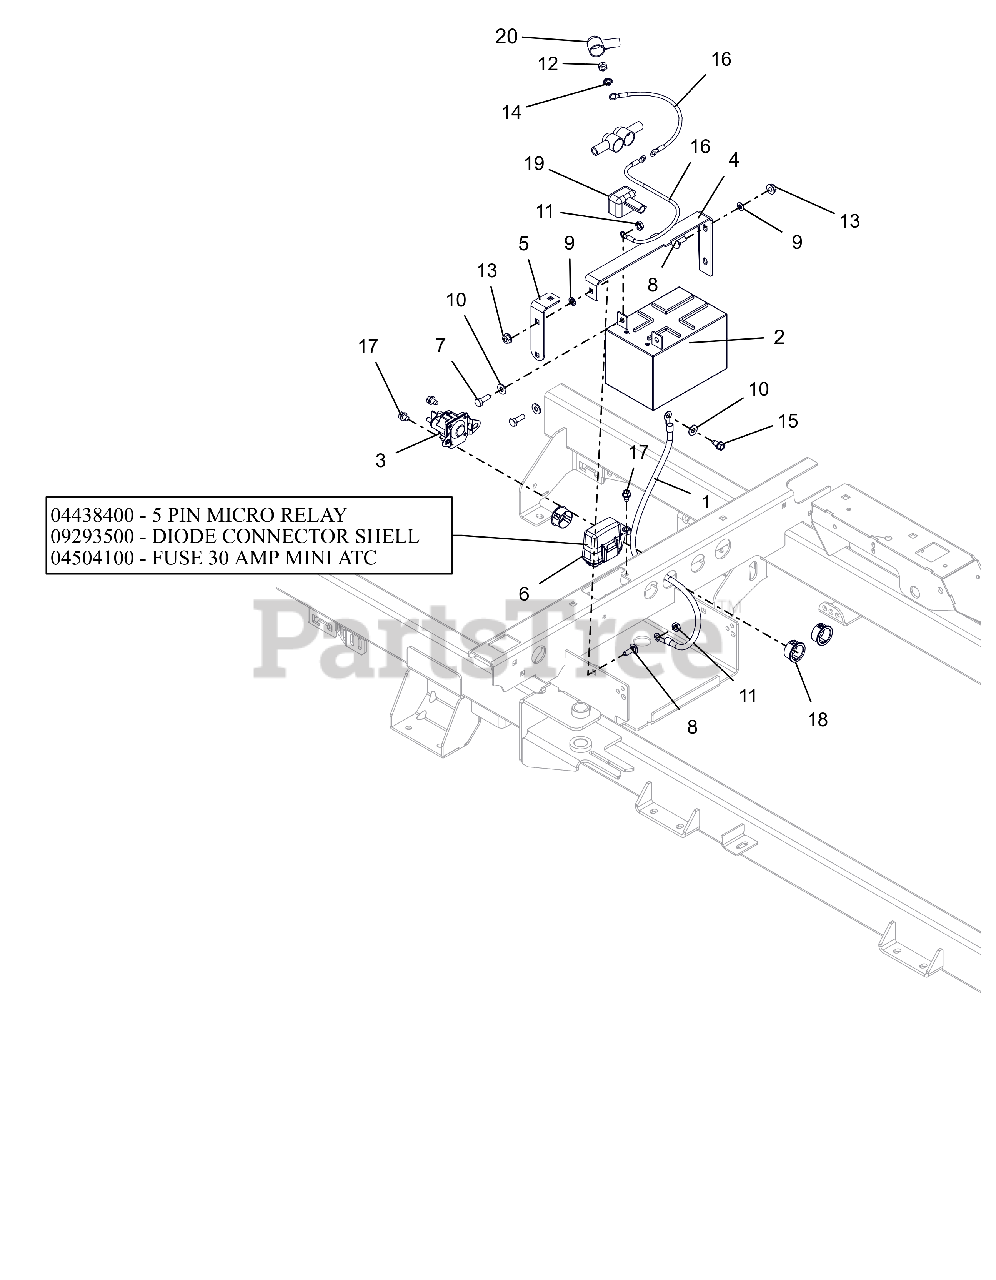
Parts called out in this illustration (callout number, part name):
1	CABLE-NEGATIVE BATTERY 24.00"
2	BATTERY, 12V 12A-190CCA
3	SOLENOID, STARTER (SEALED)
4	BRKT, BATTERY HOLD-DOWN
5	BRKT, BATTERY HOLD DOWN
6	HARNESS, WIRE-4POS KEY IKON/ZT
6	RELAY,MICRO5 TERML W/RESISTOR
6	DIODE, CONNECTOR SHELL
6	FUSE,30 AMP MINI-ATC
7	BLT, HEX .25-20X.75 G5 ZCC
8	BLT, RHSN .25-20X.750 G5 ZCC
9	NUT-PUSH .25X.50 O.D.
10	WSHR,FLT .281X.625X.065 ZCC
11	NUT-KEPS .250-20 ZCC
12	NUT-STD .250-20 G2 ZCC
13	NUT-LK-TOP-FLG .250-20 GF ZCC
14	WSHR,LK-EXT.262X.502X.026 ZCC
15	SCR-TAP .25-20X.50 HWH ZCC
16	CABLE,POS W/2 1/4 RING 15.0 LG
17	SCR,TAP .25-20X.375 HWH TR ZCC
18	BSHG, PANEL SNAP .937X1.11X.56
19	INSULATOR
20	BOOT, EYELET TERMINAL
